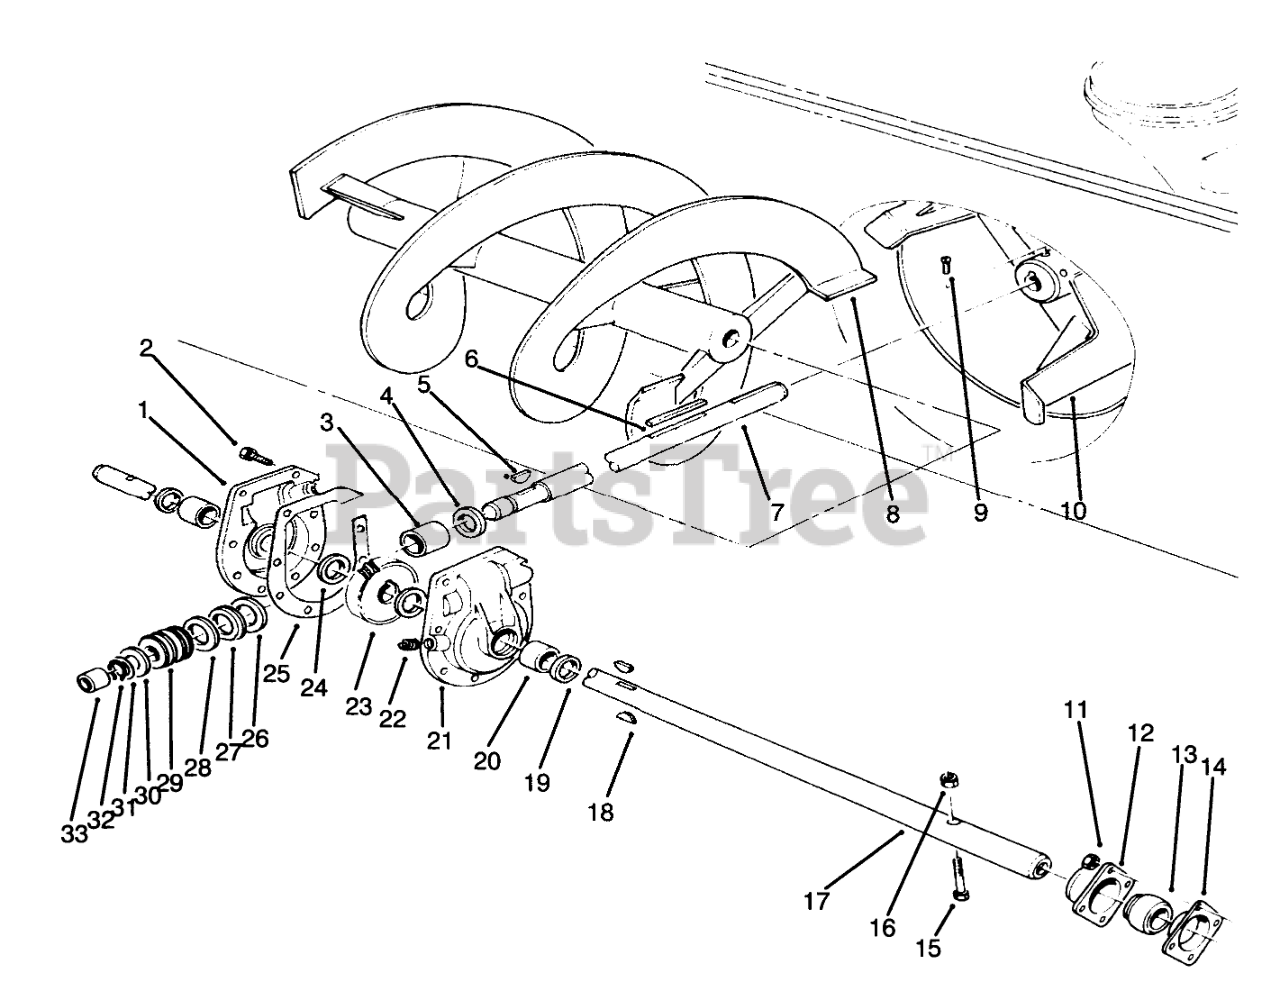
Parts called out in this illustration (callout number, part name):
1	Gear Case, R.H. Half (Incl. Ref. #19 & 20)
2	SCREW-TAPTITE
3	BUSHING-SPECIAL
4	RING-QUAD
5	KEY-WOODRUFF
7	SHAFT-IMPELLER
8	Auger RH
9	SCREW-SET, SQH
10	IMPELLER ASM
11	NUT-LOCK, NI
12	BEARING-FLANGE, FRONT
13	BEARING
14	BEARING-FLANGE, REAR
15	SCREW-HH
16	NUT-LOCK, NI
17	SHAFT-AUGER
18	KEY-WOODRUFF
19	SEAL-OIL
20	BUSHING
21	Gear Case, L.H. Half (Incl. Ref. #19 & 20)
22	PLUG-PIPE, SQH
23	GEAR-WORM, 27T
24	WASHER-THRUST
25	GASKET-GEAR BOX
26	WASHER-THRUST
27	BEARING-THRUST
28	THRUST-WASHER
30	WASHER-THRUST
31	WASHER-SHIM
32	RING-SNAP, EXTERNAL
33	BUSHING
